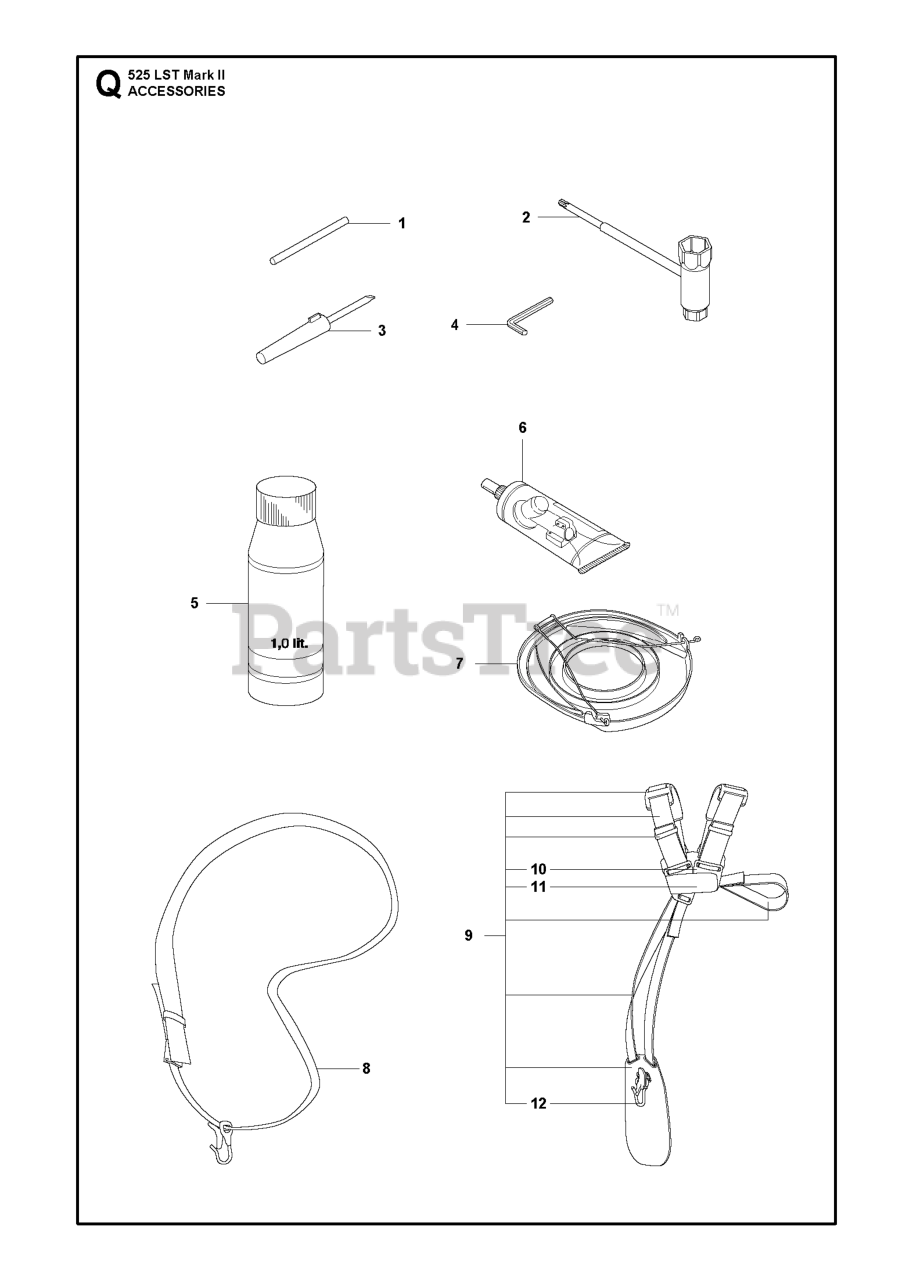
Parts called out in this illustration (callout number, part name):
1	LOCKING PIN
2	COMBINATION WRENCH TORX
3	SCREWDRIVER
4	L-KEY WRENCH
5	Air Filter Oil 1l.
6	BEVEL GEAR GREASE
7	BLADE GUARD TRANSPORT
8	Harness-w/o warning
8	Harness - Diagonal with sign
9	Harness w/warning
9	HARNESS DUO
12	HOOK, CPL.
